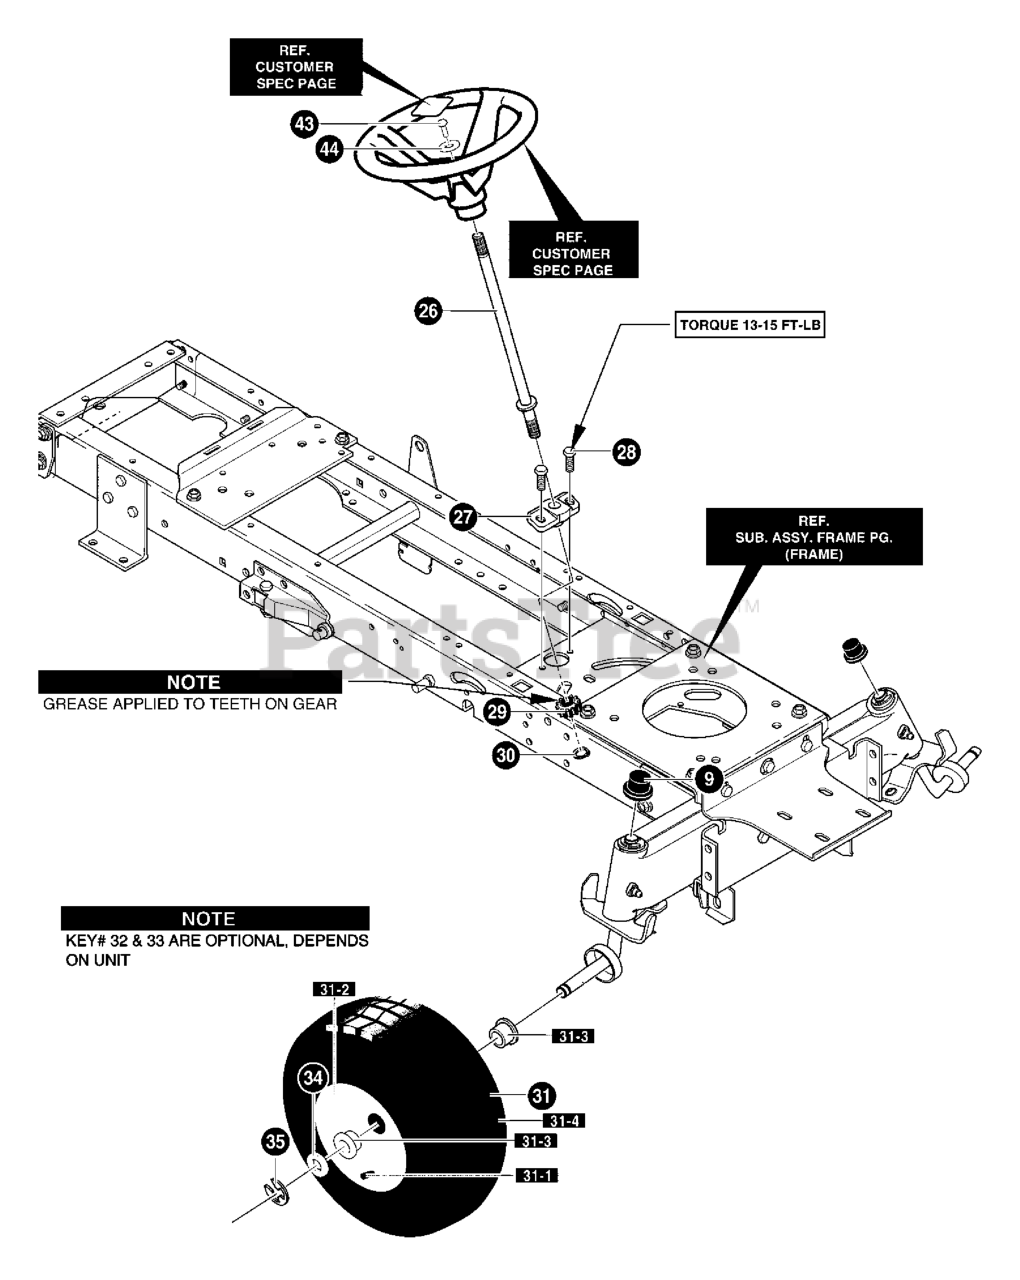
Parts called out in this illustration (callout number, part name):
9	DUST HUB CAP
26	SHAFT, STEERING BOLT ON
27	BEARING-LOWER
28	SCREW, 5/16-18 x .75 HHWATAP
29	GEAR PINNION
30	RING, RET E.
31	TIRE & RIM 15X6.00-6
31-1	VALVE STEM
31-3	BEARING
31-4	TIRE 15X6.00-6
34	WASHER, FLAT .765 x 1.81 x .059
35	E-RING .574IDX.050/.750SH
43	SCREW, 1/4-20X.75
44	FLATWASHER .281X1.25X.06
